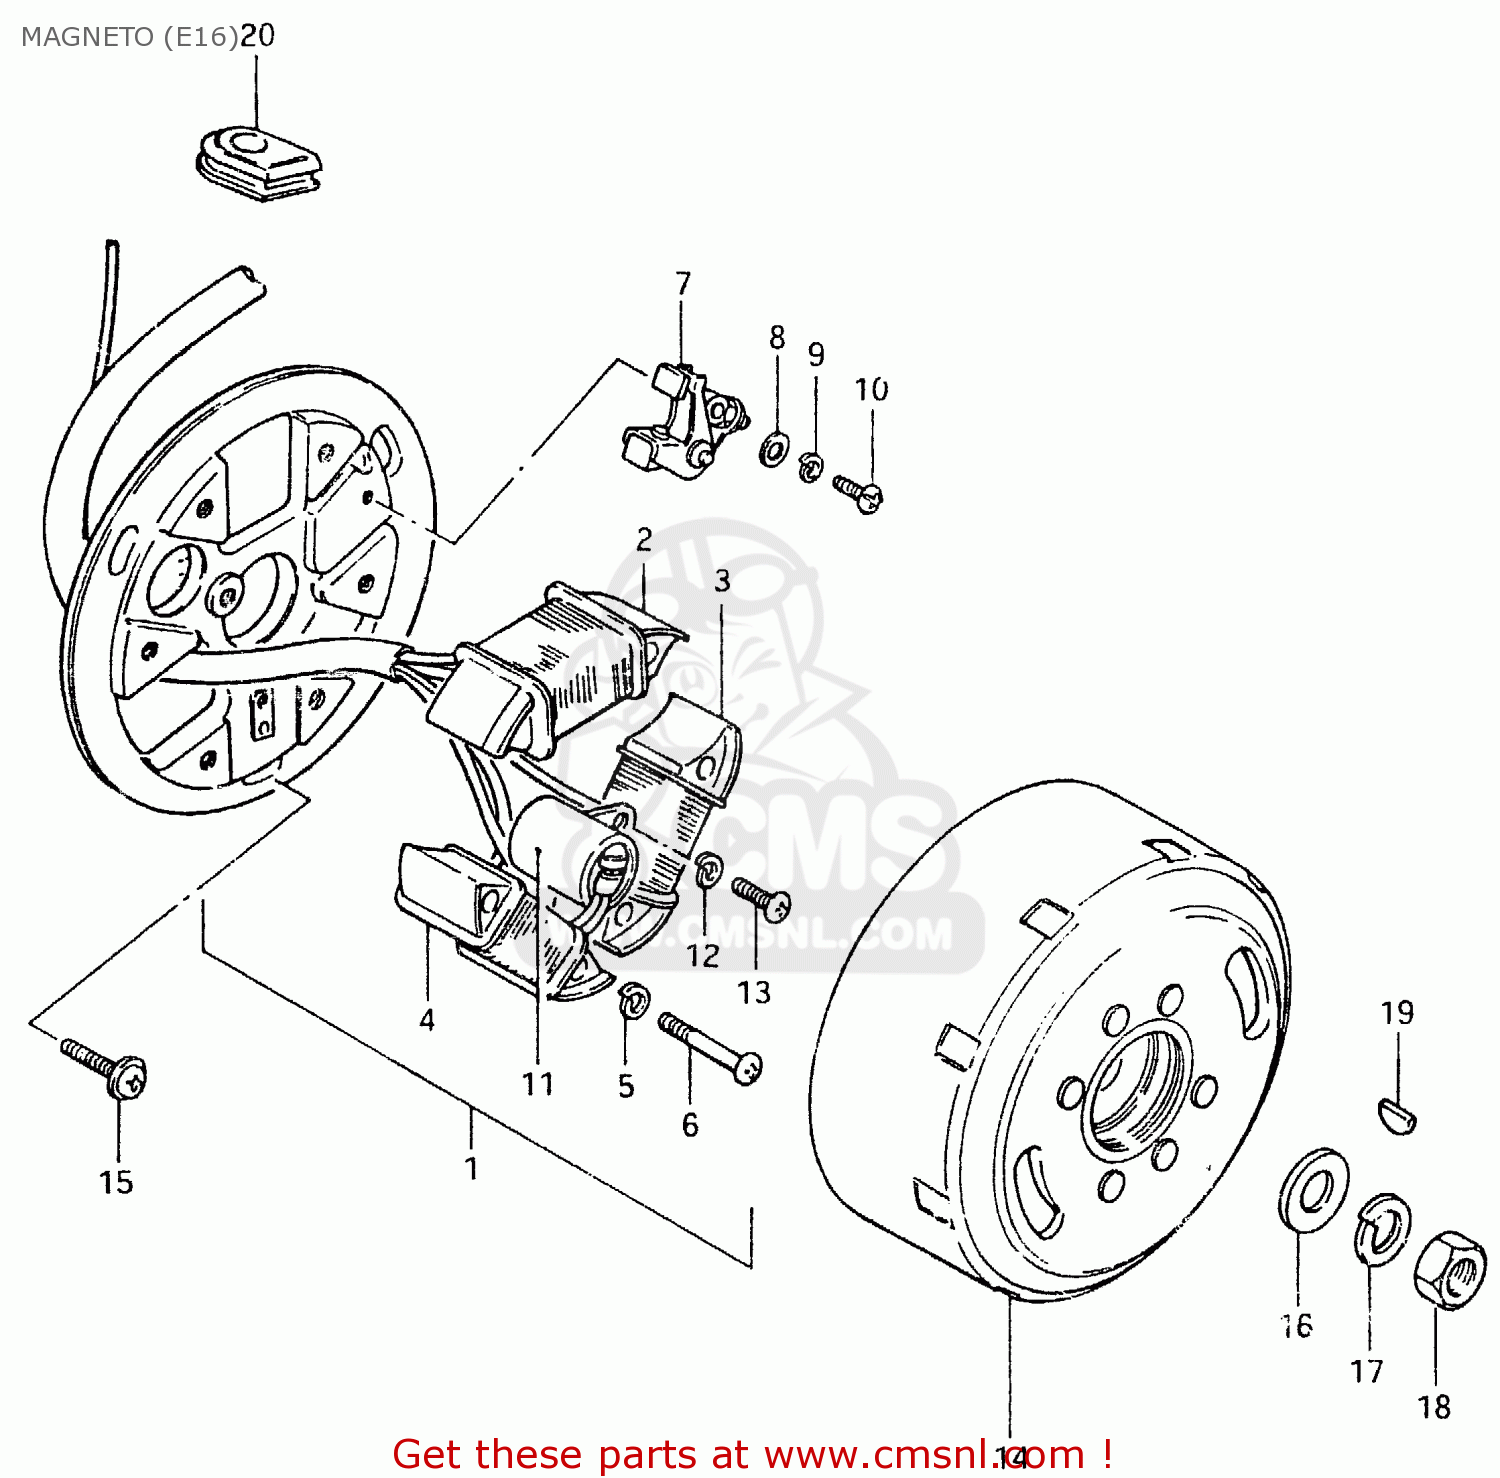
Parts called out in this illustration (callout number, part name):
1	STATOR ASSY
2	COIL, LIGHTING (A)
3	COIL, LIGHTING (B)
4	COIL, PRIMARY
5	LOCK WASHER
6	SCREW (4X30)
7	POINT ASSY,CONTACT
8	WASHER
9	LOCK WASHER
10	SCREW(4X10)
11	CONDENSER
12	LOCK WASHER
13	SCREW 4X6
14	ROTOR
15	SCREW(5X14)
16	WASHER
17	LOCK WASHER
18	NUT (10MM)
19	KEY
20	GROMMET
